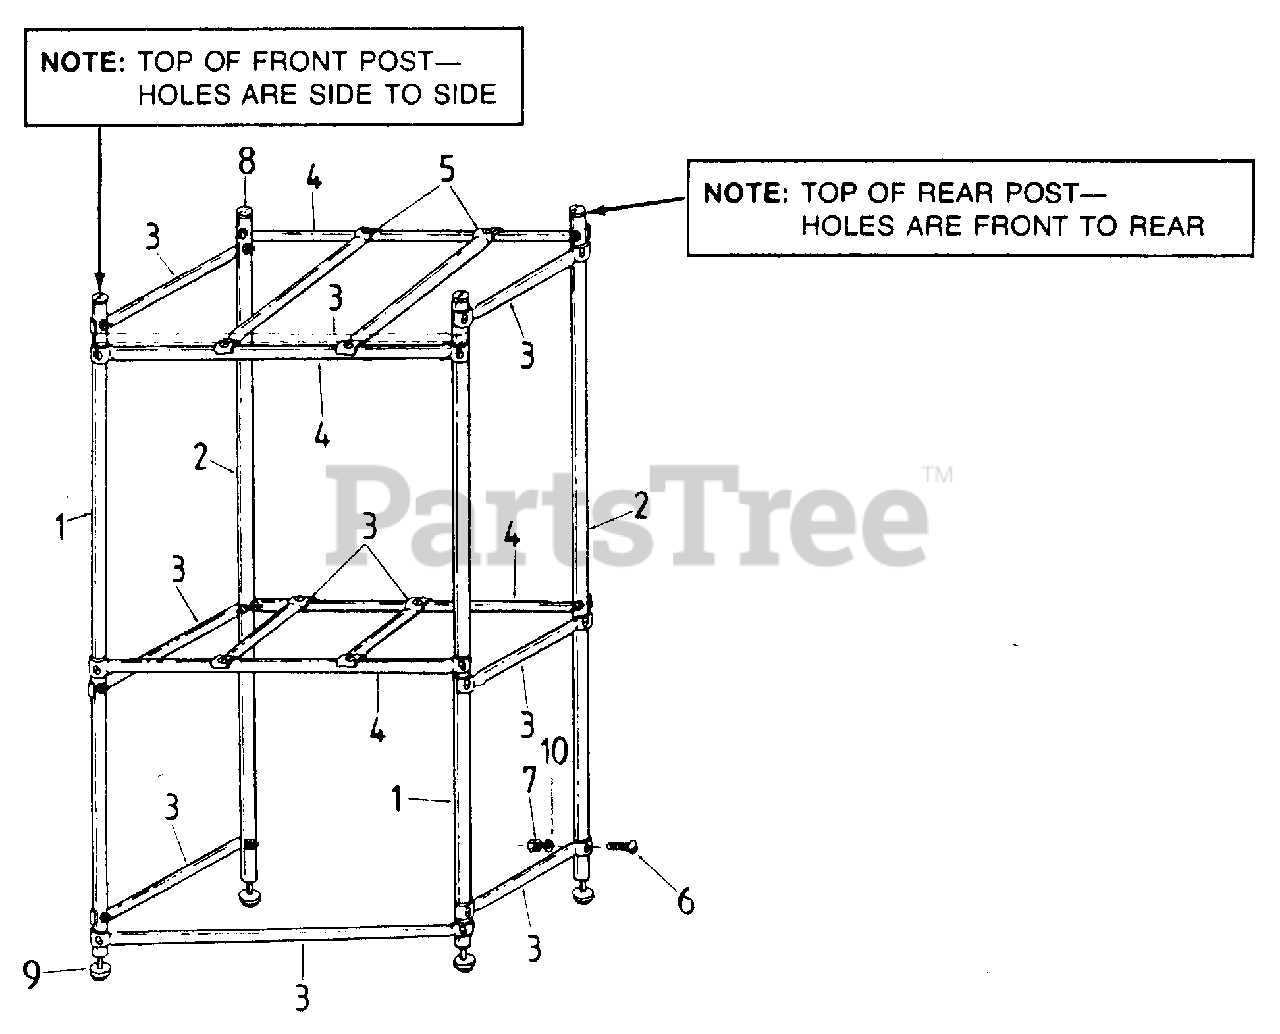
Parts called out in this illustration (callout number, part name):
3	Cross Brace w/o Center Holes 31" Lg. (Tubing parts)
6	Truss Mach. Screw 1/4-20 x 1-1/2" Lg.
7	Hex Nut 1/4-20 Thd.
8	1" Tubing Plug
9	1" Swivel Glide
10	Lock Washer 1/4" I.D.
